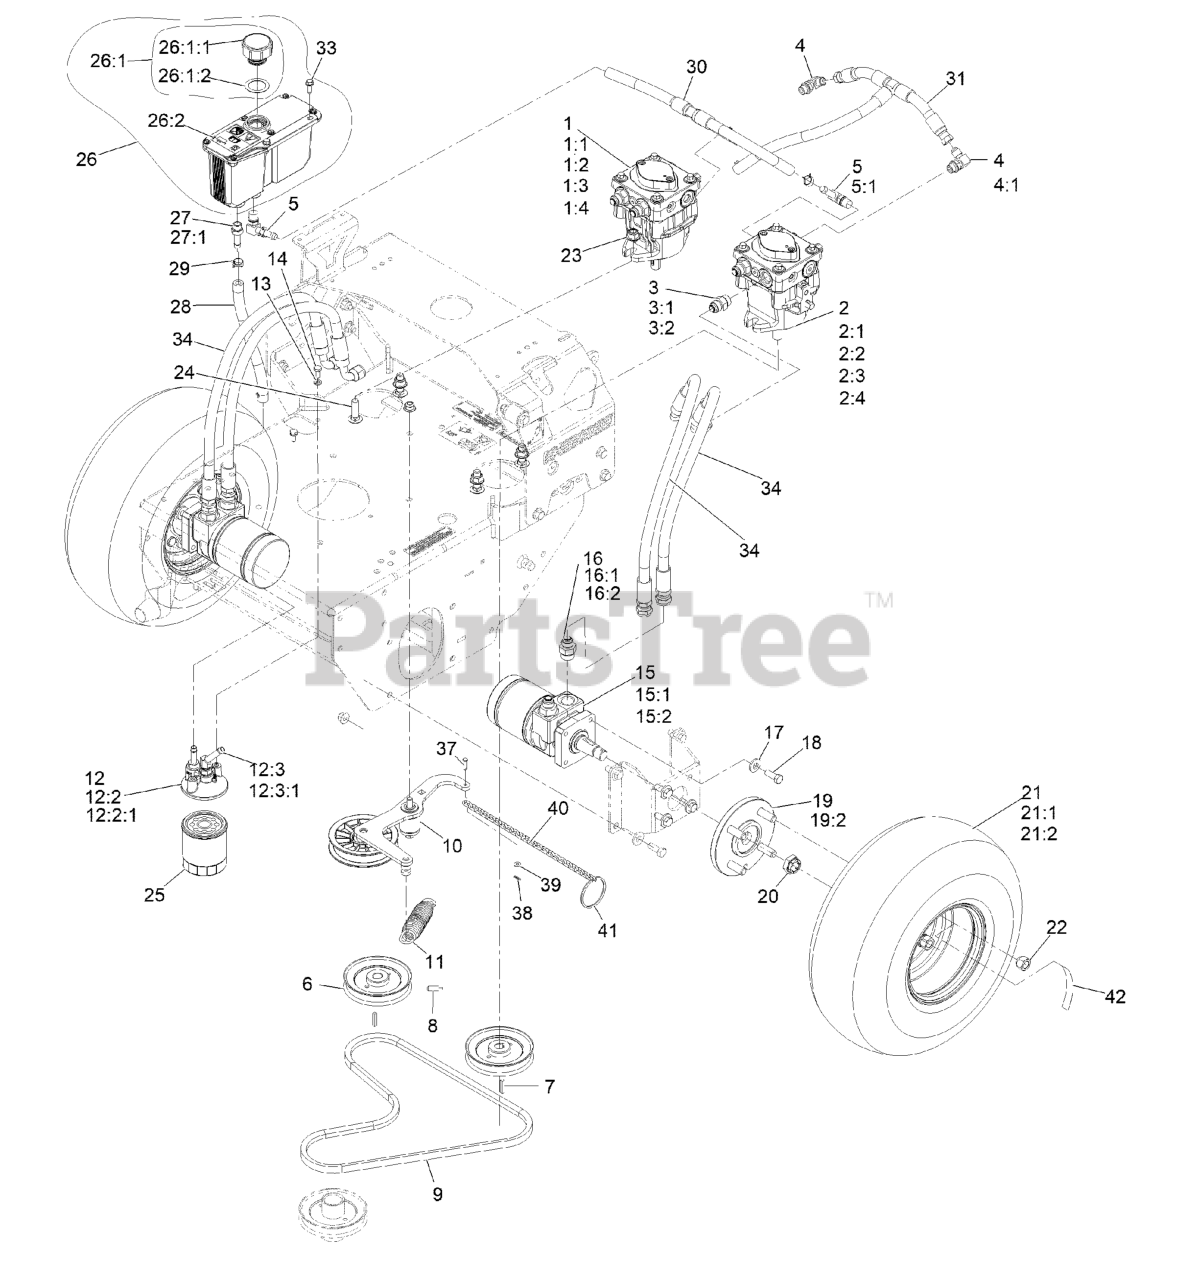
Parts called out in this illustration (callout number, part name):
1	RH HYD PUMP ASM
1:1	INPUT SHAFT KIT
1:2	BEARING-THRUST
1:3	CYLINDER BLOCK KIT
1:4	SEAL OVERHAUL KIT
2	LH HYD PUMP ASM
2:1	INPUT SHAFT KIT
2:2	BEARING-THRUST
2:3	CYLINDER BLOCK KIT
2:4	SEAL OVERHAUL KIT
3	FITTING-STRAIGHT
4	FITTING-ELBOW, 90 DEG
4:1	O-RING
5	FITTING-ELBOW, 90
5:1	O-RING
6	SHEAVE ASM
8	SCREW-SET, SQH
9	BELT
10	ASM, PUMP IDLER
11	SPRING-EXTENSION
12	ASM, FILTER HEAD
12:2	ADAPTER-STRAIGHT
12:2:1	O-RING
12:3	FITTING-BARBED, 45 DEG
12:3:1	O-RING
13	WASHER-LOCK
14	SCREW-HH
15	HYD MOTOR ASM
15:1	SEAL KIT
15:2	BEARING AND SEAL KIT
16	FITTING-STRAIGHT
16:1	O-RING
17	WASHER-BELLEVILLE
18	SCREW-HH
19	WHEEL HUB ASM
19:2	STUD-WHEEL
20	NUT-LOCK
21	WHEEL AND TIRE ASM
21:1	TIRE-TURFMASTER
21:2	RIM-WHEEL
22	NUT-LUG
23	NUT-HF, NI
24	BOLT-CARR
25	FILTER-25 MICRON, BI-DIRECTIONAL
26:1	Reservoir-HYD
26:1:1	Cap-Reservoir, HYD
26:1:2	GASKET-CAP
26:2	DECAL-WARNING
27	ADAPTER-STRAIGHT
27:1	O-RING
28	HOSE-CHARGE
29	CLAMP-HOSE
30	HOSE-CASE DRAIN
31	HOSE-CHARGE
33	SCREW-HWH, THREAD ROLL
34	HYD HOSE ASM
37	PIN-CLEVIS
38	PIN-HAIR
39	WASHER-PLAIN
40	CHAIN-LINK, TWIST
41	RING-SPLIT
42	DECAL-TORQUE WHEEL LUG-HU
